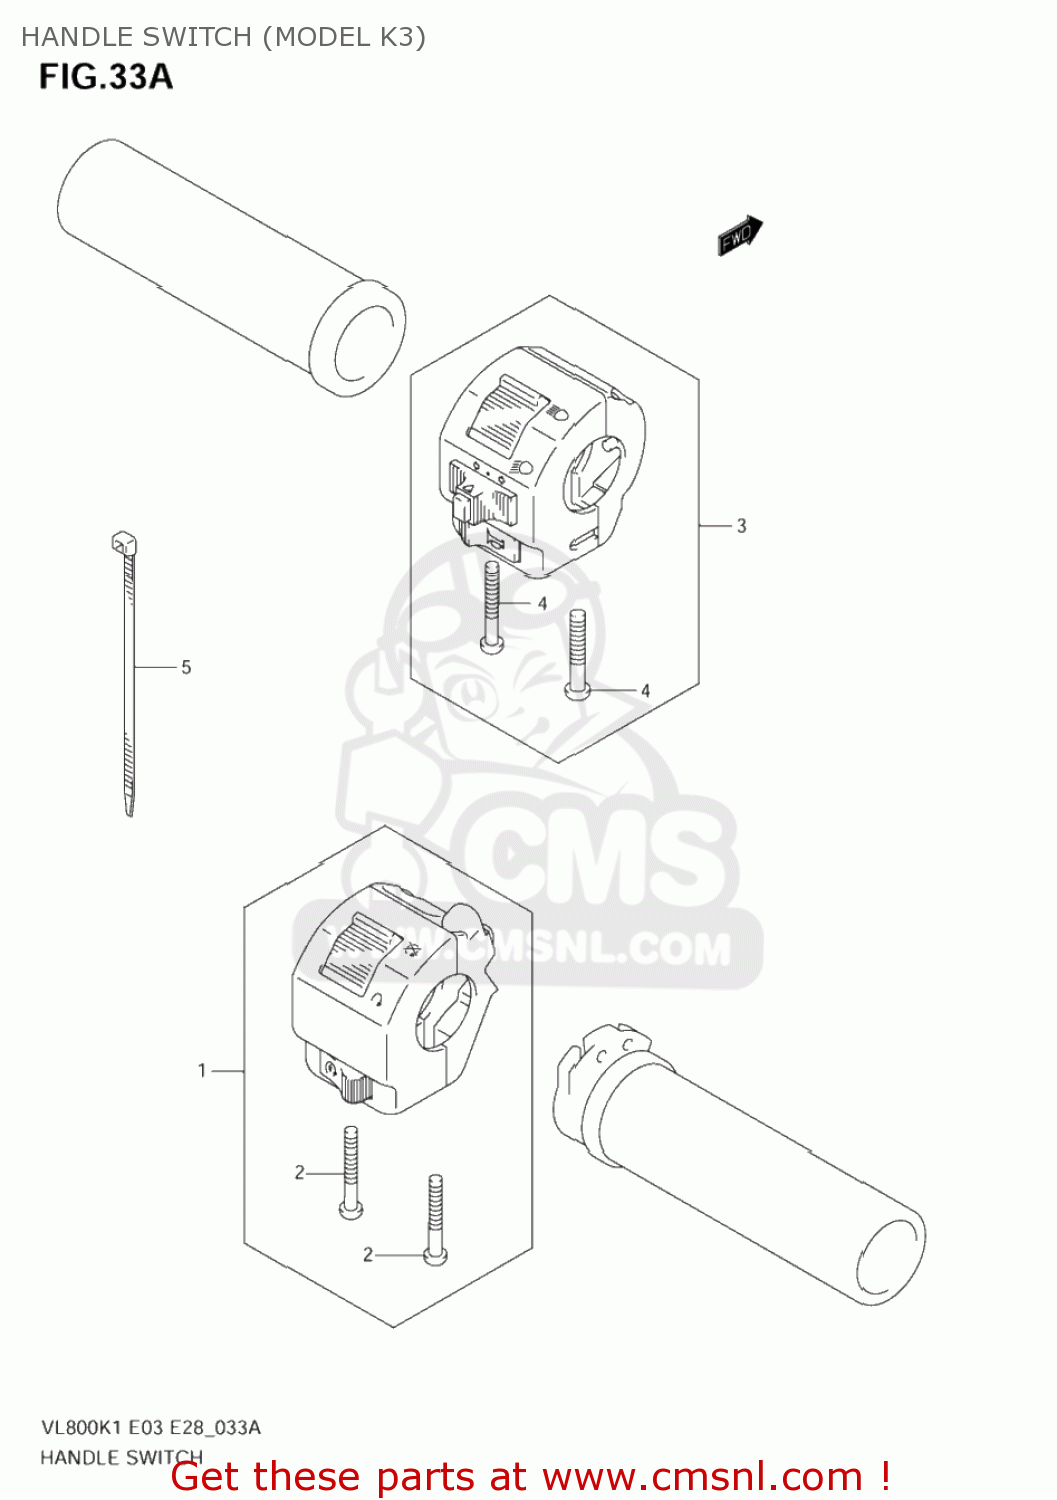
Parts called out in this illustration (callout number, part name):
1	SWITCH ASSY,HANDLE,R
2	SCREW(5X16)
3	SWITCH ASSY,HANDLE,L
4	SCREW(5X16)
5	CLAMP(L:145)
